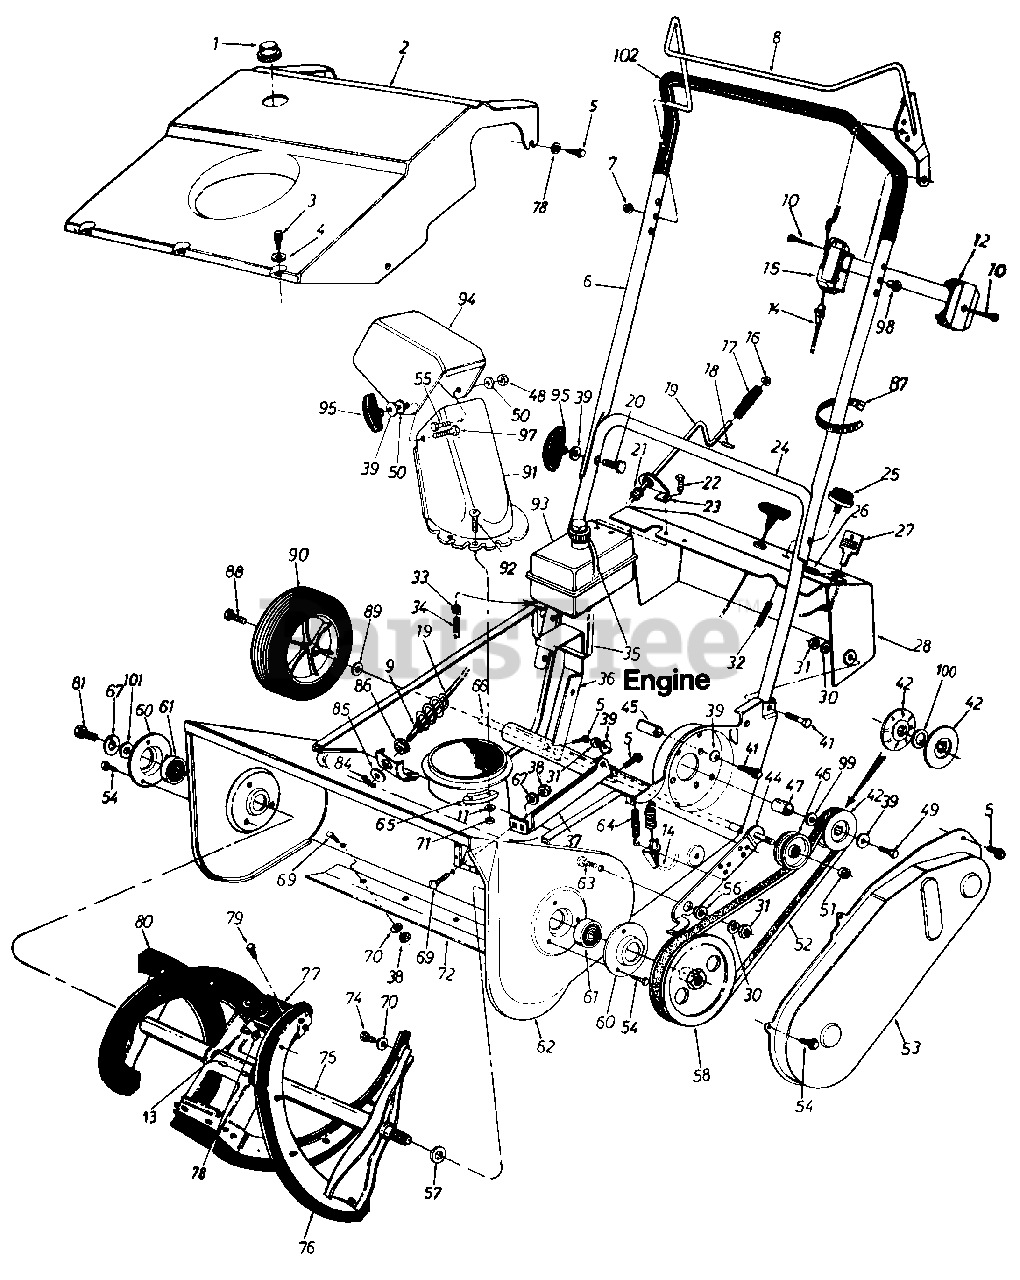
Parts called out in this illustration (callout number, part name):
1	Gas Tank Cap
2	21" Shroud
3	Hex B-Tap Scr. #10 x .38"
4	Spr.-Wash. .206" I.D. x .448"
5	Hex L-Wash. Hd. AB-Tap 1/4 X .62" Lg.
8	Control Handle Ass'y. L.H.
9	Fl-Wash. 385" I.D. x .62"
10	Truss Mach. Hi-B Tap Scr. #12 x 1.5" Lg.
11	Fl-Wash. .281" I.D. x .5" O.D.
12	Control Panel Half
13	Pop Rivet .188" Dia.
14	Clutch Cable 35" Lg.
15	Control Panel Half
16	Push Cap 3/8" Rod
17	Knob 3/8" Dia. Hole
18	Roll Pin 1/8" Dia. x .63" Lg.
19	Chute Crank Ass'y.
20	Curved Carriage Bolt 5/16-18 x 1.75" Lg.
21	Chute Crank Grommet
22	Hex AB-Tap Scr. 1/4 X .75" Lg.
23	Upper Chute Crank Brkt.
26	Plastic Plug
27	Plastic Key
31	Hex Nut 5/16-18 Thd.
32	Primer Hose 11" Lg.
33	Hose Clamp 1/2" Dia.
34	Gas Line 12" Lg.
35	Cable Tie 17.75" Lg.
38	Hex Jam Nut 1/4-20 Thd.
39	Bell-Wash. .345" I.D. x .88"
41	Hex Bolt 5/16-18 x 1.5" Lg.
42	3/8" "V"-Pulley Half .625" I.D. x 6.0" O.D.
46	Fl-Idler w/Flanges 2.12" O.D.
47	Spacer .635" I.D. x.89" O.D. x .57
48	Hex L-Nut 5/16-18 Thd.
49	Hex Bolt 5/16-24 x .75" Lg.
50	Fl-Wash. .344" I.D. x 1.25
51	Hex Patch L-Nut 3/8-24 Thd.
52	"V"-Belt
54	Hex B-Tap Scr. 1/4" x .38" Lg.
55	Carriage Bolt 5/16-18 x .75"
56	Shld. Spacer .50" Dia. x .27"
57	Fl-Wash. .510" I.D. x 1.0" O.D.
58	3/8" "V"-Pulley '/2-20 L.H. x 6"
64	Extension Spring 1.12" Lg.
65	Chute Flange Keeper
66	Wheel Axle 1/2" O.D. x 20.6" Lg.
67	L-Wash. 1/4" I.D..
69	Carriage Bolt 1/4-20 x .50"
70	Fl-Wash. .281" I.D. x .73"
71	Hex L-Nut 1/4-20 Thd.
72	Shave Plate
74	Hex Wash. B-Tap Scr. 1/4 x .62"
76	Rubber Spiral L.H.
77	Rubber Paddle
78	Fl-Wash. .218" I.D. x .62"
79	Hex Wash. B-Tap Scr. #10 x .62" Lg.
80	Rubber Spiral R.H.
81	Hex Wash. TT-Tap Cl-Scr. 1/4-20 x .75" Lg.
84	Cotter Pin 3/32" Dia. x .75"
85	Fl-Wash. .406" I.D. x 1.25"
86	Hex Bushing .385" I.D.
87	Cable Tie
88	Hex Tap Scr. 3/8-24 x .5" Lg.
89	Fl-Wash. .510" I.D. x .75"
90	Wheel & Tire Ass'y. 7" x 1.5"
91	Lower Chute
92	Truss Mach. Scr. 1/4-20 x .75"
93	Fuel Tank Two Qt.
94	Upper Chute
95	Knob Handle Ass'y.
97	Carriage Bolt 5/16-18 x 1"
98	Control Disc Pin
99	Fl-Wash. .635" I.D. x 1.04" O.D.
100	Fl-Wash. .635" I.D. x .93" O.D.
101	Fl-Wash. .25" I.D. x .93"
102	Foam Grip 22" Lg.
